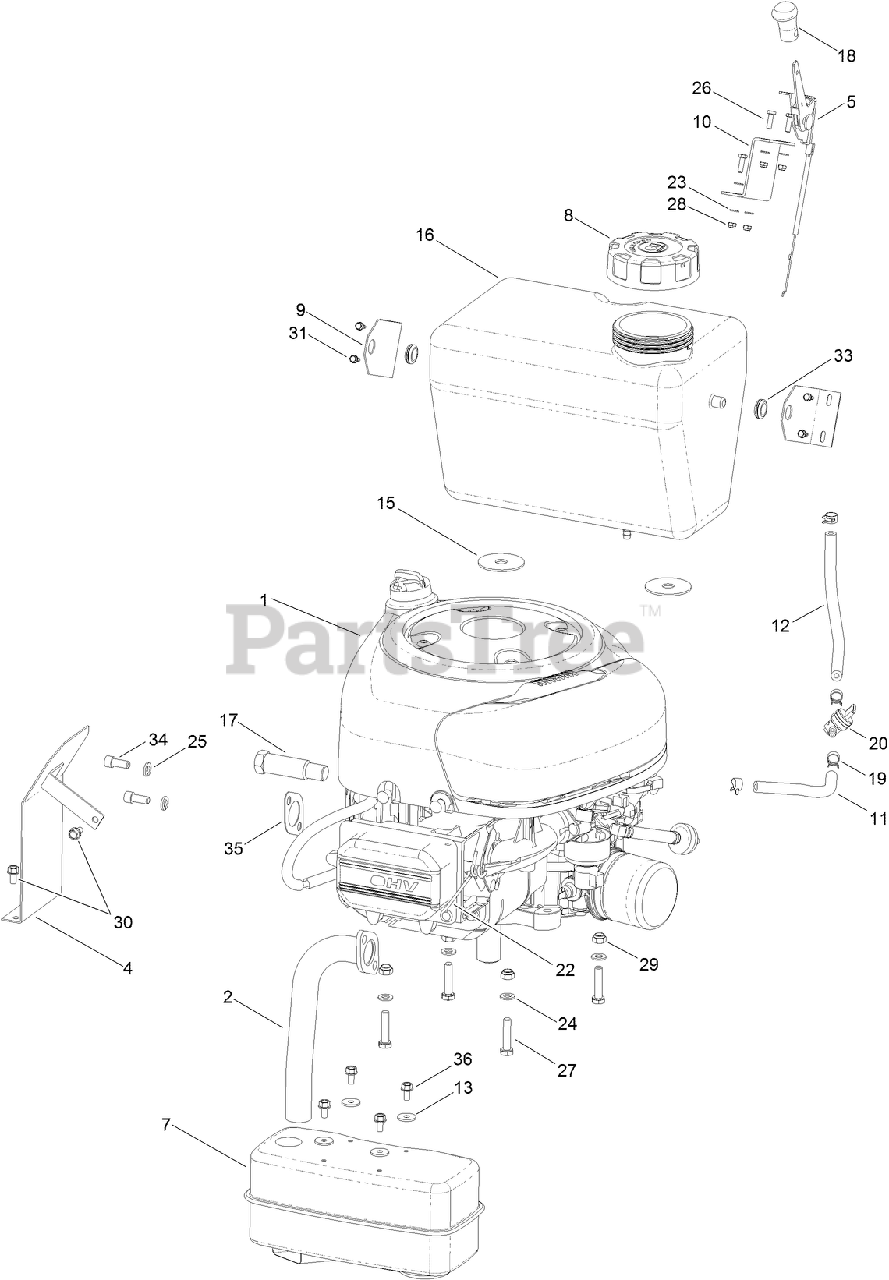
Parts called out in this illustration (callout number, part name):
2	TUBE-EXHAUST
4	COVER-EXHAUST
5	CABLE-THROTTLE/CHOKE
7	MUFFLER
8	CAP-FUEL
9	BRACKET-FUEL, TANK
10	HOLDER
11	LINE-FUEL
12	LINE-FUEL
13	WASHER-FLAT
15	WASHER-RUBBER
16	TANK-FUEL
17	COUPLER-DRAIN, OIL
18	KNOB-THROTTLE/CHOKE
19	CLAMP-LINE, FUEL
20	VALVE-TANK, FUEL
22	HOLDER-HARNESS, WIRING
23	WASHER
24	WASHER-PLAIN
25	WASHER-SPRING
27	SCREW-HH
28	NUT-LOCK
29	NUT-LOCK, NI
30	SCREW-HH
31	SCREW-TAP
33	BUSHING
34	SCREW-HH
35	GASKET
36	SCREW-HHTF
